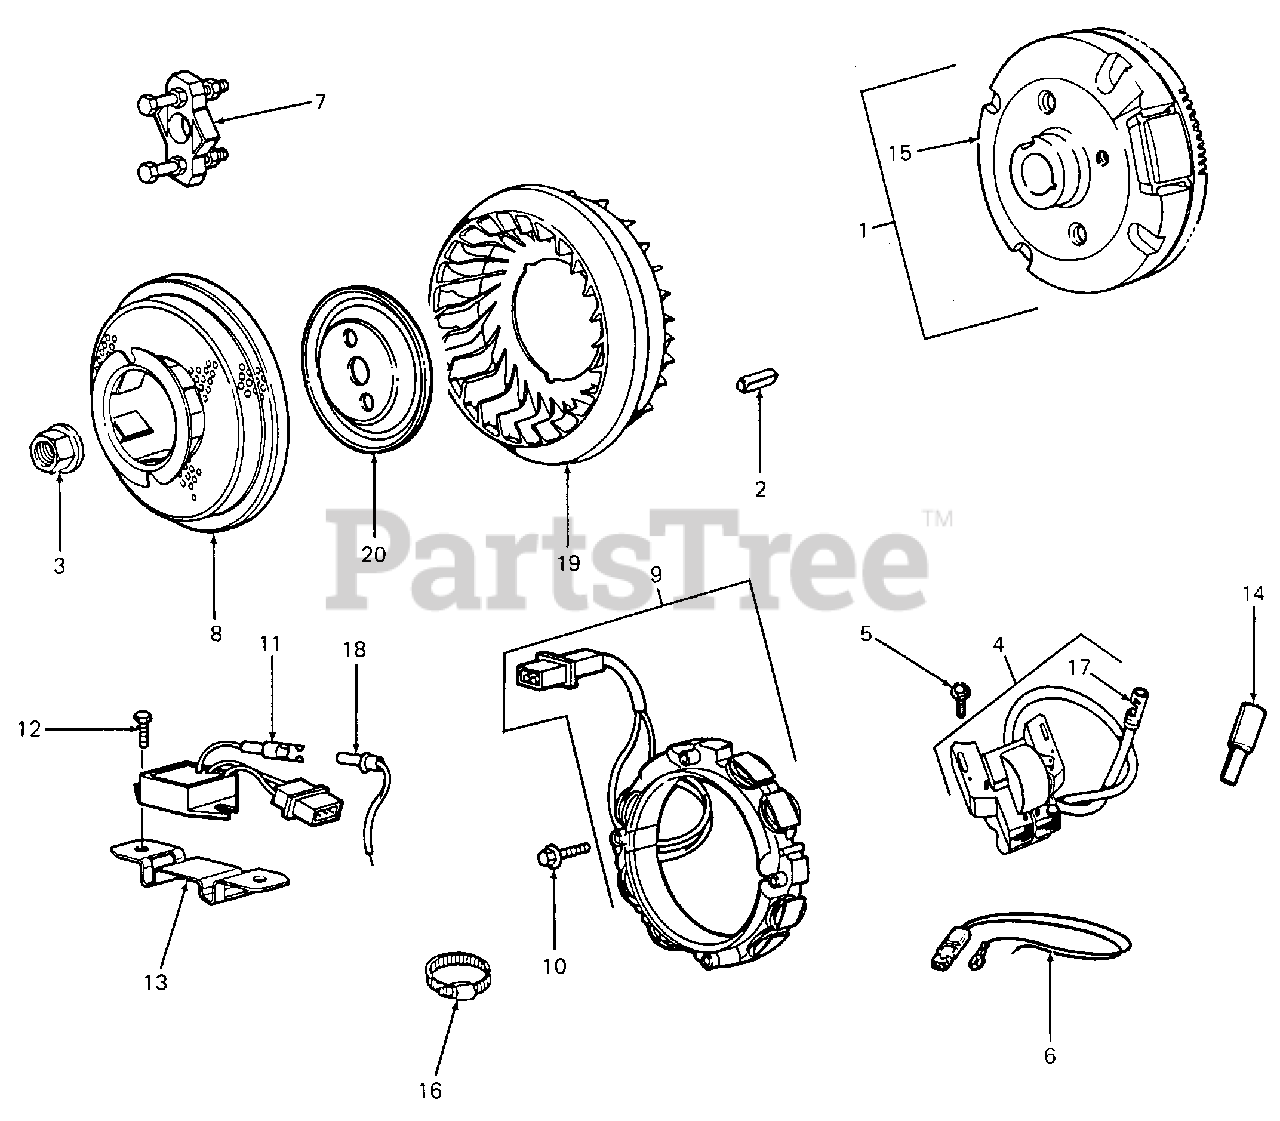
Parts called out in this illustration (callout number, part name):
1	Flywheel, Magneto
2	Key, Flywheel
4	Armature
5	Screw, Sems
6	Wire, Ground
7	Puller, Flywheel
8	Hub & Screen Assy, Starter
9	Stator, 16 Amp
10	Screw, Sems
11	Regulator, Alternator
13	Bracket, Regulator
14	Elbow, Spark Plug
15	Gear, Ring
16	Clamp, Regulator
17	Terminal
18	Harness Assy, Alternator
19	Fan, Flywheel
20	Retainer, Fan
